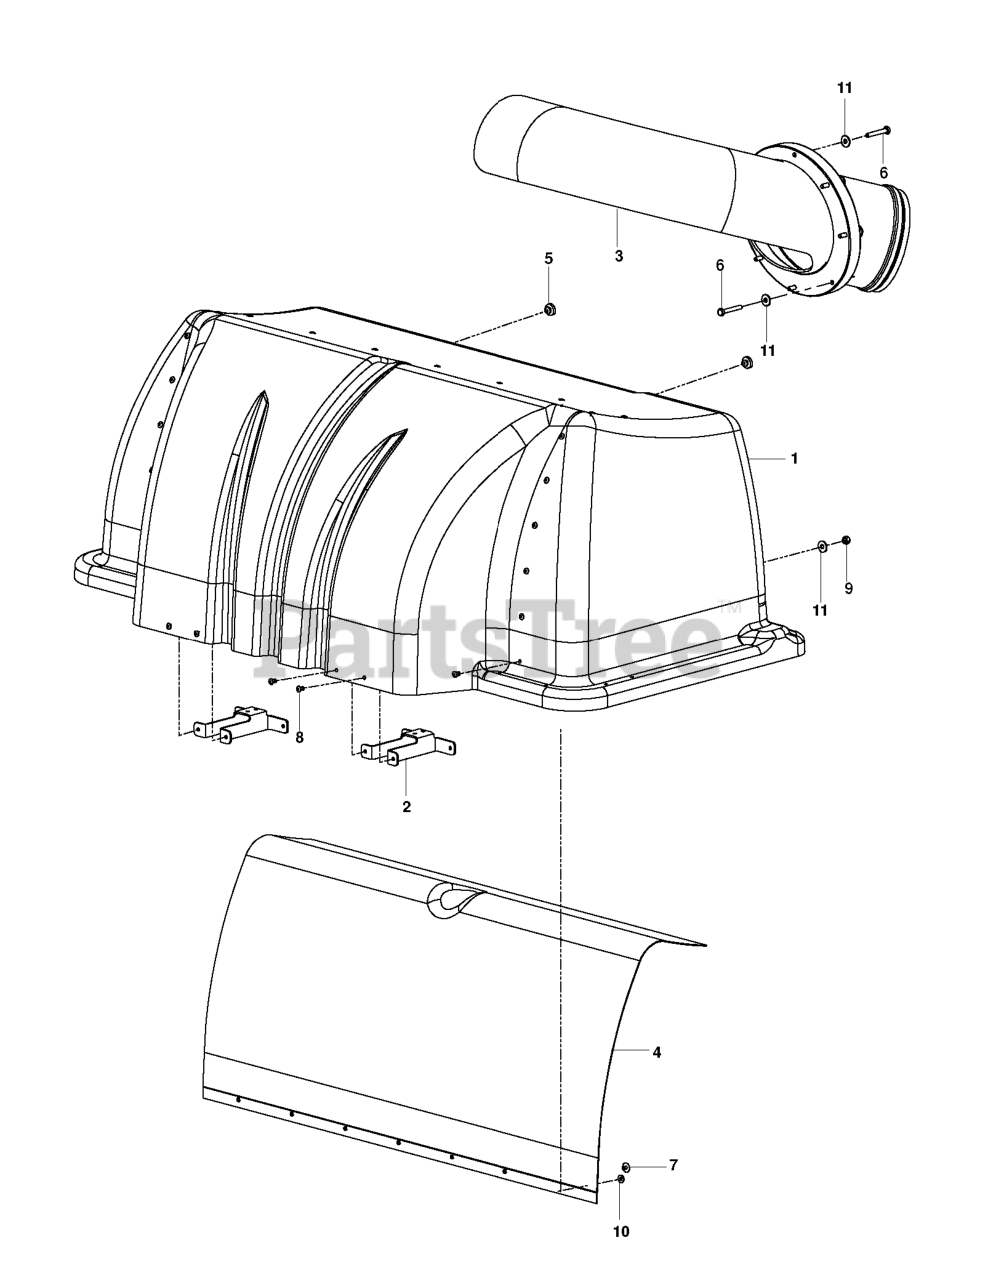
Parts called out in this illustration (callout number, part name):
2	SUPPORT, DRAW LATCH
4	MESH, POLY DIAMOND
5	GROMMET, BUMPER
6	BOLT 1/4C X 1 3/4
7	NUT.1/4-20.HEX.NYLOC.ZD
8	WASHER 1/4 FLAT
9	NUT.1/4-20.HEX.NYLOC.ZD
10	RIVET E/16 X 1/4 LG FLG
